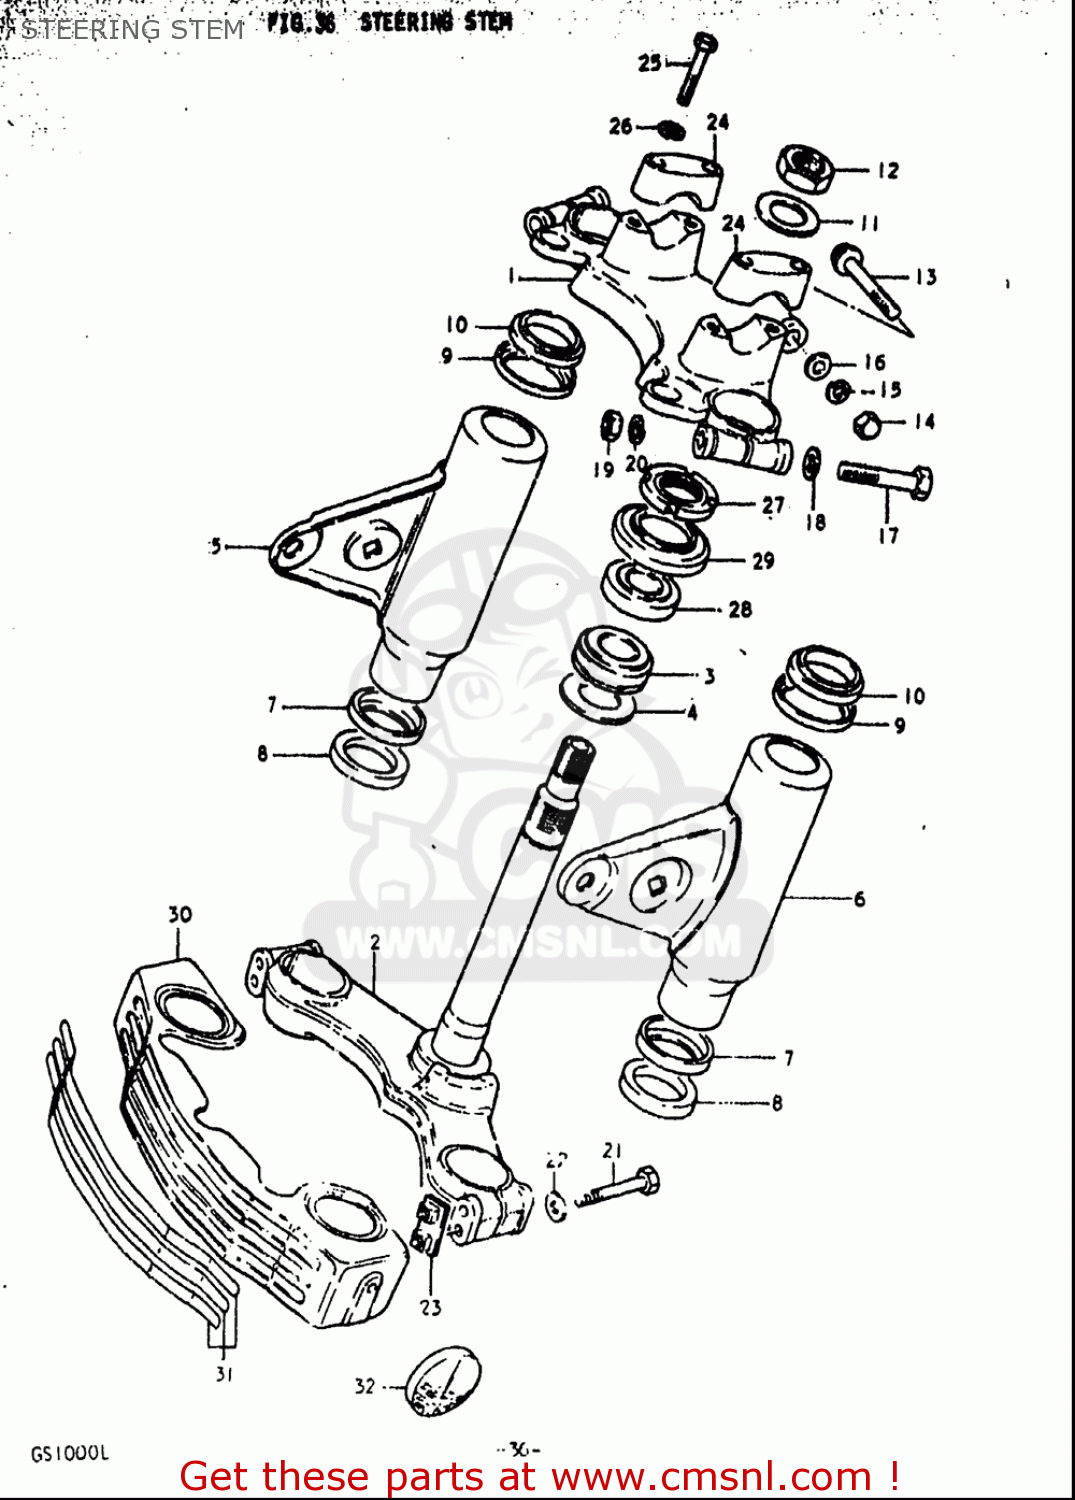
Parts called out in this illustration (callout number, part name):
3	BEARING(30X55X17)
4	SHIM(30X40X1.5)
11	WASHER
12	NUT,FR FORK UPR BRACKET
13	BOLT, LH
14	NUT
15	WASHER,LOCK
17	BOLT
18	WASHER
19	NUT
20	WASHER,LOCK
21	BOLT
22	WASHER,LOCK
23	NUT,FR FORK INNER TUBE
24	HOLDER,HANDLE(BLACK)
25	BOLT
26	WASHER,LOCK
27	NUT,STEERING STEM(25X44X10)
28	BEARING(25X47X15)
29	SEAL,STEERING UPR DUST
32	REFLEX REFLECTOR,RR
